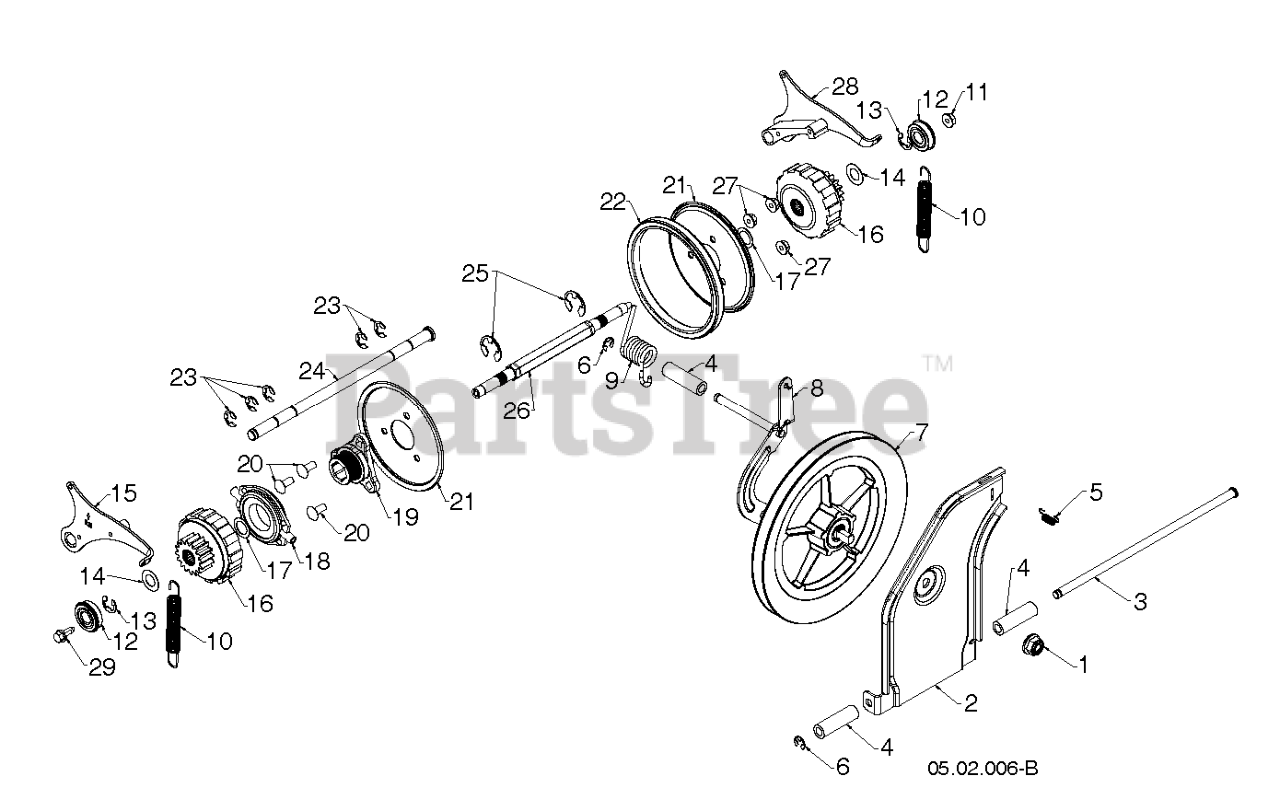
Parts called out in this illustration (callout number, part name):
1	NUT 1/2-13 HEX FLANGE NYLOK CL
3	ROD ROD,PIVOT, SWING PLATE ROD
4	SPACER YOKE, TORSION SPRING
5	SPRING LATCH
6	RETAINER RING E-RING CLEAR ZI
7	PULLEY ASSY TEXTURED TEXTURED
8	BRACKET.YOKE.ASSEMBLY.479
9	SPRING TORSION DRIVE
10	SPRING EXTENSION PS
11	NUT.HEX.FLANGE.LOCK.5/16-18
12	BEARING 9/16 ID. SNR
13	RING.RETAINING.1622-2RSNR.CLER
14	WASHER FLAT.637IDX1.00ODX21GA
15	PAWL.ASM.RH.SNOW
16	GEAR.ASM.PLANETARY
17	WASHER FLAT.59IDX1.065ODX25GA
18	BEARING HOUSING ASSY TRUNNION
19	HUB.RUBBER.WHEEL
20	RHSNB 5/16-18 X 3/4 GR5 BLK ZN
21	PLATE.RUBBER.WHEEL.BLACK
22	Friction Drive
23	CLIP E-RING_.500 SHAFT
24	ROD ROD, PAWL ROD
27	NUT.LOCK.5/16-18
28	PAWL.ASM.LH.SNOW
29	SCREW HEXAGON HEAD FLANGE 5/16
